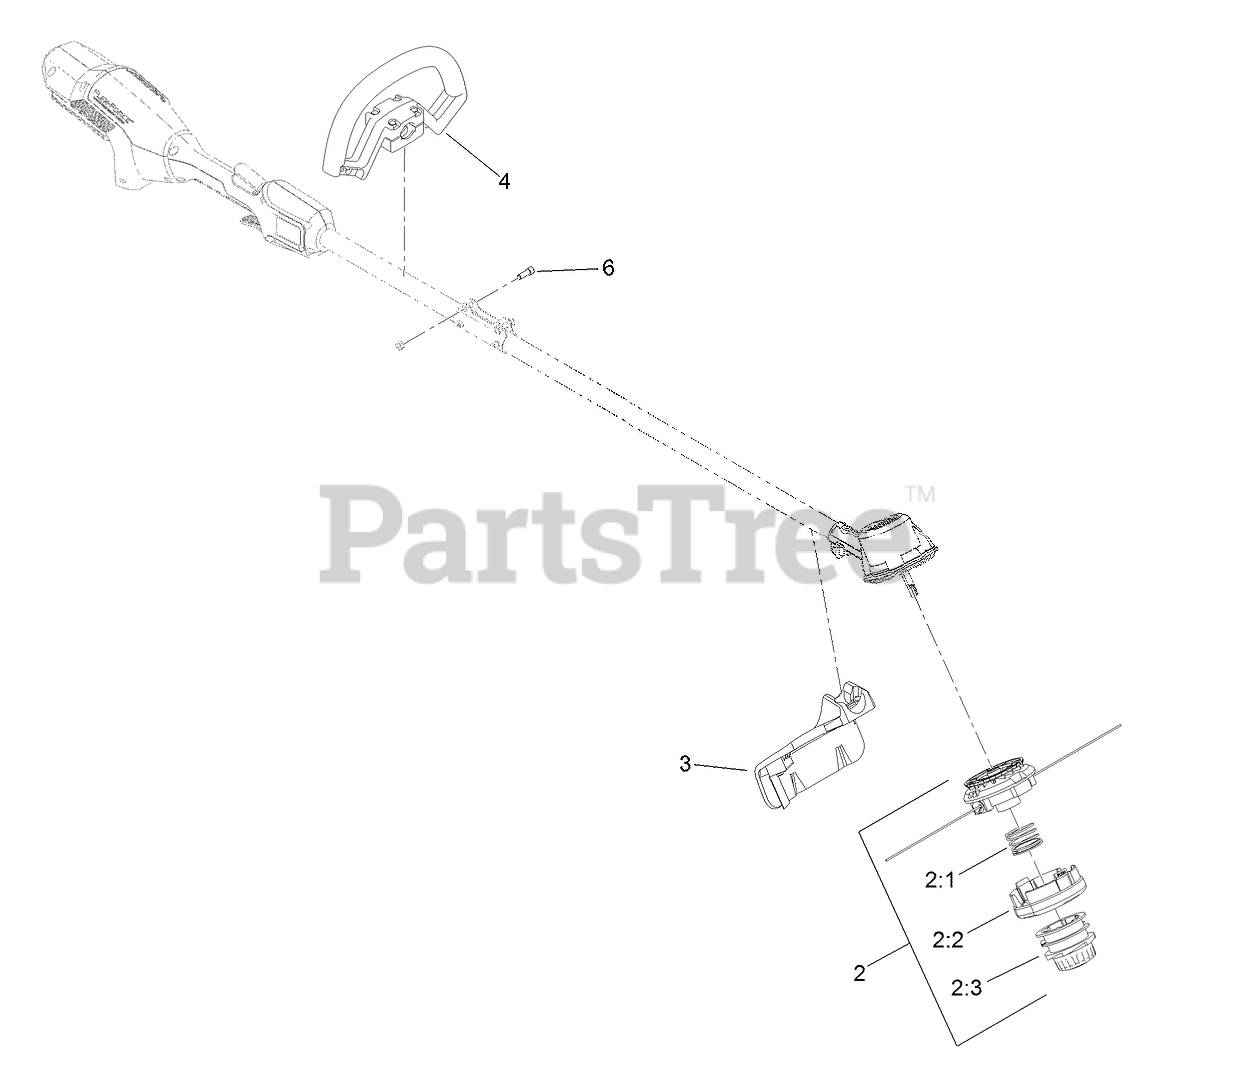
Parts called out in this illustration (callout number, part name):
2	BUMP FEED HEAD ASM
2:1	SPRING-SPOOL
2:2	CAP-FEED, BUMP
3	SHIELD-GRASS
4	HANDLE-TRIMMER
6	SCREW-HSH
